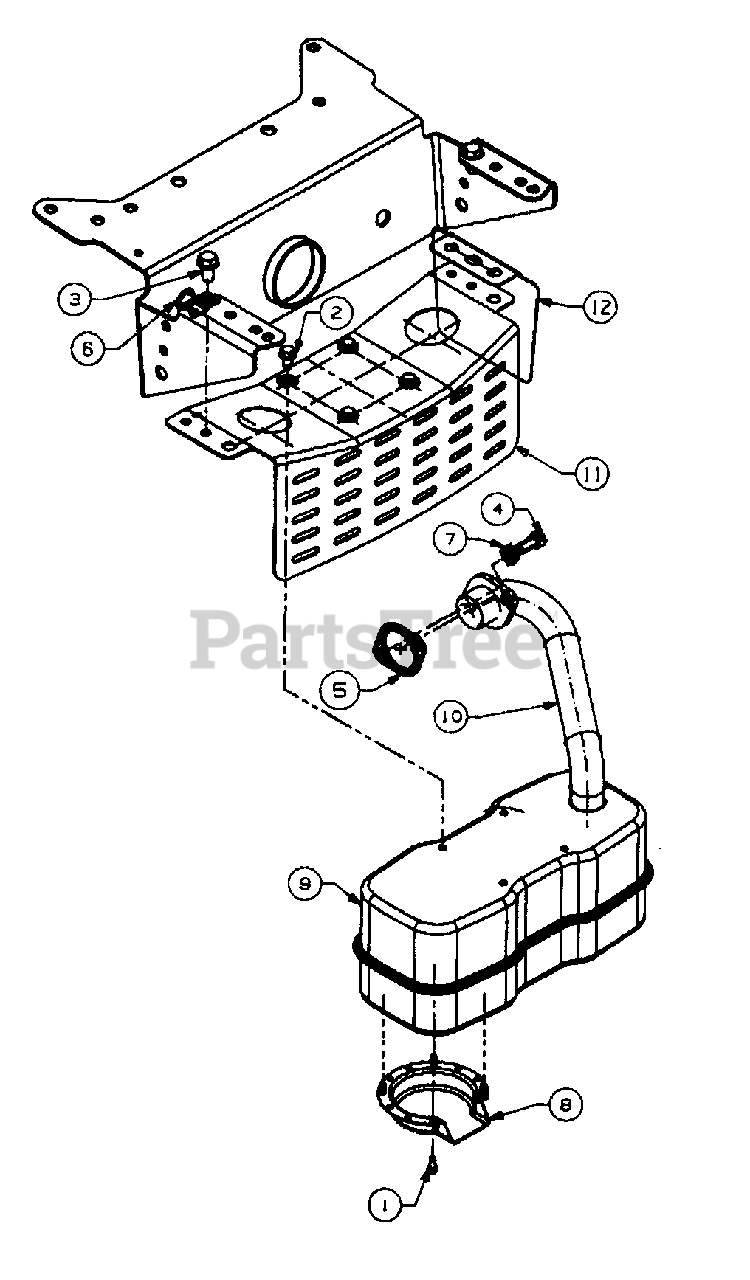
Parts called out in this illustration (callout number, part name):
1	Hex Slot Scr. #8-32 x .38" Lg.
2	Hex Wash. TT-Tap Scr. 1/4-20 x .5" Lg.
3	Hex Wash Hd. TT-Tap Scr. 5/16-18 x .62" Lg.
4	Socket Hd. Bolt 5/16-18 x .62" Lg.
5	Exhaust Gasket
6	Clamp
7	L-Wash. 5/16" I.D.
8	Muffler Deflector
9	Muffler
10	Exhaust Pipe
11	Muffler Bracket
12	Shield Bracket
